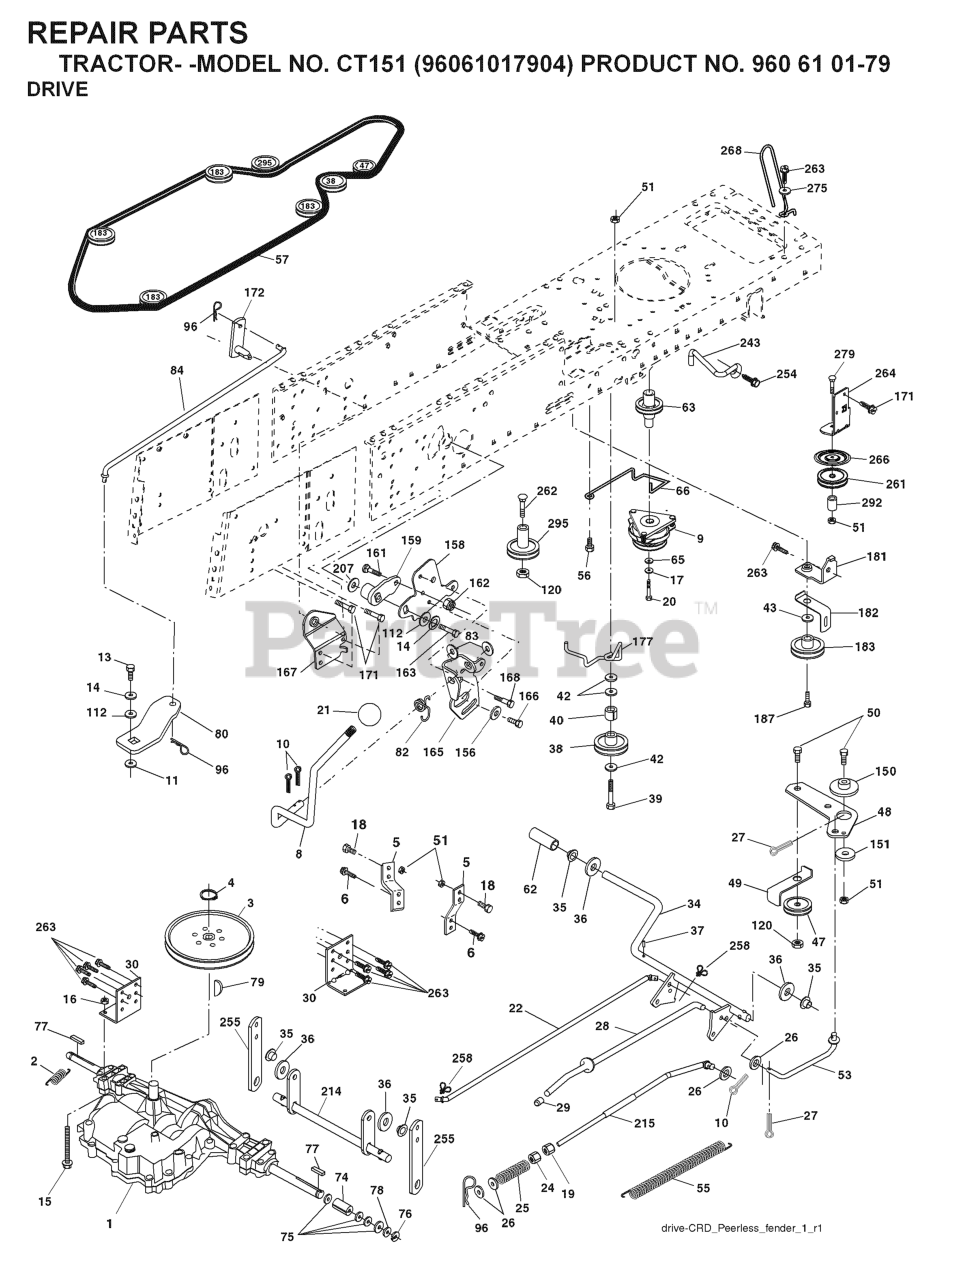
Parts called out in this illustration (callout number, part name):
2	SPRING,BRAKE RETURN
3	PULLEY
4	RETAINING RING LT
5	STRAP TORQUE
6	SCREW 5/16"
8	ROD SHIFT FENDER ADJUST LT
10	PIN COTTER
11	WASH-SHFT PLT LT
13	BOLT 1/4-28X3/4
14	LOCKWASHER
15	BOLT HEX 5/16-18 GR 5
16	NUT.71038.31-18.HEX.NYLOCK
18	BOLT
19	NUT
20	BOLT HEX 7/16-20X4-1/4"
21	KNOB.DUCKHEAD.1/2
22	ROD
24	NUT
25	SPRING ROD LT
26	WASHER
27	COTTER PIN
28	ROD, PARKING BRAKE
29	CAP
30	BRKT, MOUNT TRNSAXLE
34	SHAFT, FOOT PEDAL
35	BEARING.NYLON
36	WASHER LT
37	DRIVE PIN
38	PULLEY.FLAT
42	WASHER
43	WASHER T
47	IDLER PULLEY
48	BELLCRANK, CLUTCH
49	RETAIN BELT
50	BOLT.3/8-16X1.50
53	LINK.CLUTCH.7.66.2005
55	SPRING, RETURN LT
56	SCREW.3/8-16
57	V-BELT.KEV.111"
62	PEDAL COVER T
63	PULLEY.ENGINE.CVX.LT
65	LOCKWASHER
66	KEEPER BELT ENGINE
74	SPACER AXLE
77	SQUARE KEY
79	KEY STD (1373) DANA
82	SHIFT SPRING
83	WASHER
96	RETAINER M
112	WASHER LT
120	NUT LOCK FLG 3/8-16 UNC
150	BUSHING.BELLCRANK.GRD.DR
151	WASHER 12/32X2X10GA
156	WASHER.SRRTD.5/16
158	BRACKET
159	RB HUB.SHIFT
161	BOLT
162	NUT.CROWNLOCK.1/4
163	BOLT
165	RP BRACKET
166	CAPSCREW.HXHD.FLG.5/16-18X.625
167	BRACKET.SUPT.SHIFT.CRD
168	BOLT.SHOULDER.5/16-18X
171	SCREW LT
172	SHAFT
181	BRACKET
182	BELT GUIDE
183	PULLEY.V-IDLER.GRND.DR
187	BOLT.5/16-18X1.25
207	WASHER NYL
214	LEVER
243	BRACKET, ANTI-ROTATION
254	SCREW 3/8-16X1
255	SHAFT
258	CLIP RETAINER
261	FLAT IDLER PULLEY
263	SCREW, 3/8-16X3/4
266	PROTECTOR
268	GUARD MUFFLER
275	WASHER
279	BOLT
292	SPACER
295	PULLEY IDLER COMPOSITE
